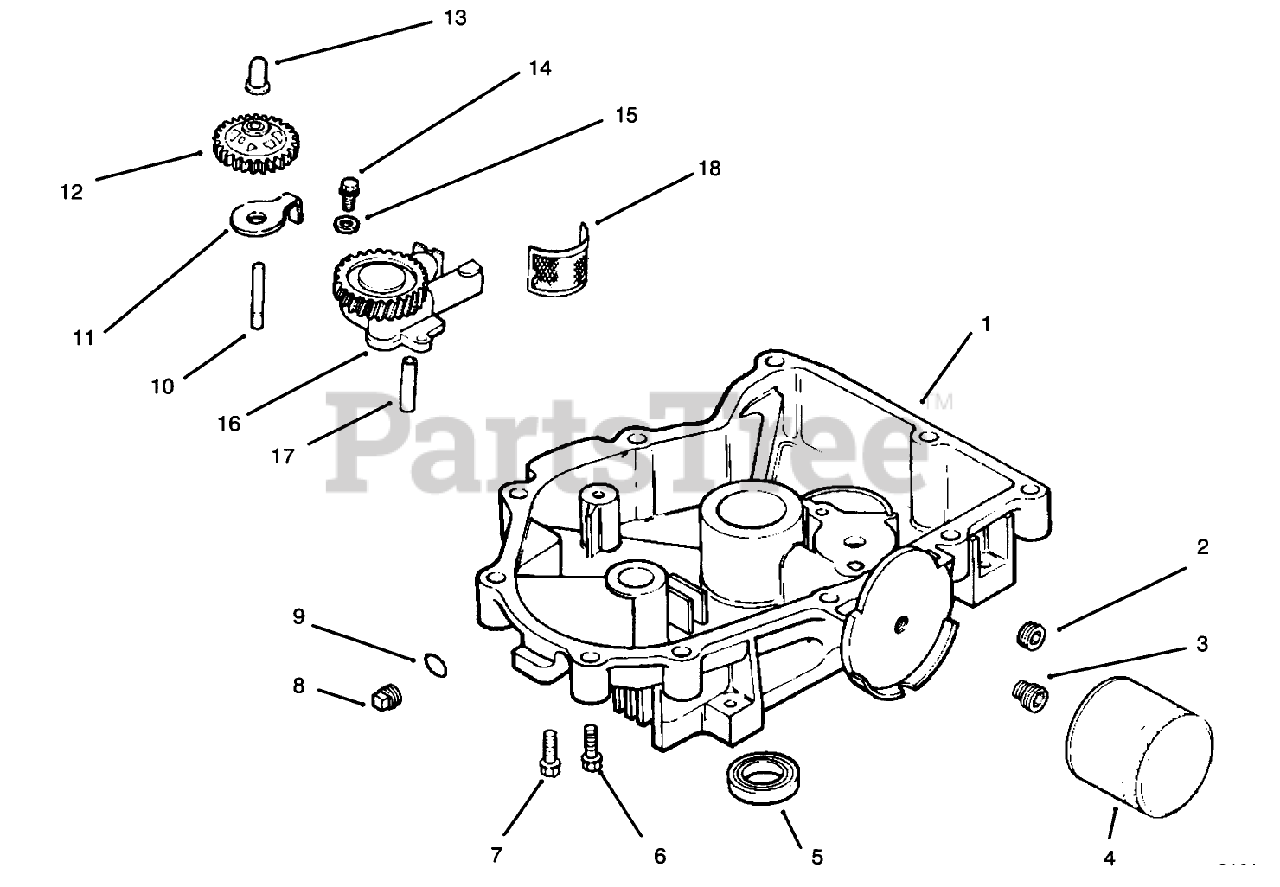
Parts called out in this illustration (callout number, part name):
1	Pan-Oil
3	Nipple-Oil Filter
4	Filter-Oil
5	Seal-Oil
6	Screw
7	Screw
10	Shaft-Govenor Gear
11	Tab-Locking
12	Kit-Governor Gear Assembly (Incl. Ref. #7)
13	Pin-Governor
16	Oil Pump ASM INC 16
17	Tube-Oil Pickup (Only On: 72103, 72083)
18	Screen-Oil
